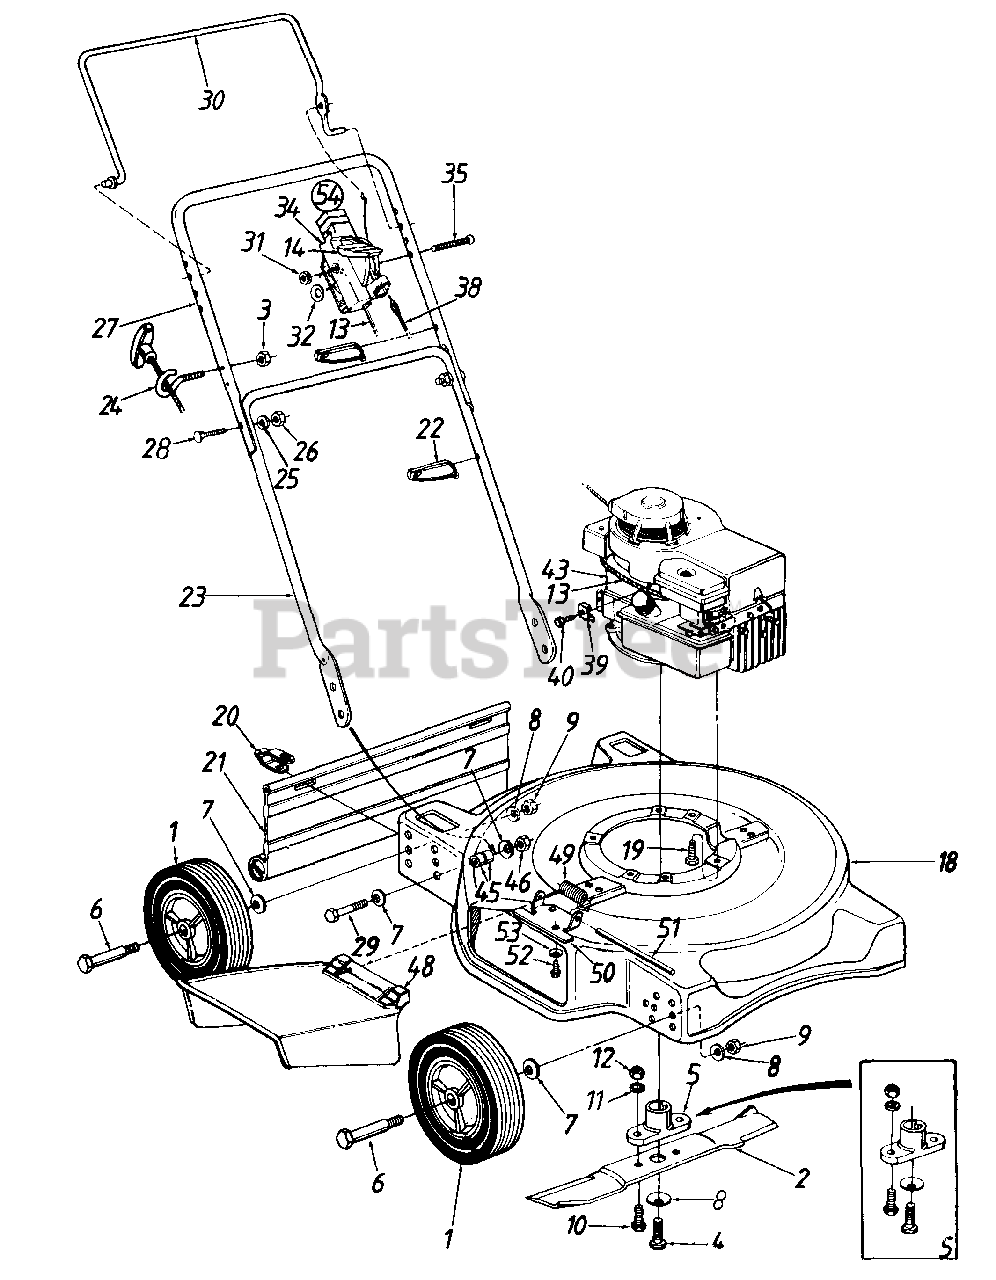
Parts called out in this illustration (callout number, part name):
1	Wheel Ass'y. Comp. Rib Tread Plastic Rim (7")
2	20" Blade
3	Hex L-Nut 1/4-20 Thd.
4	Hex Bolt 3/8-24 x 1.5" Lg.
5	Blade Adapter Kit
6	Axle Bolt
7	Bell-Wash..380" I.D. x .88"
8	Bell-Wash..39" I.D. x 1.13"
9	Hex Nut 3/8-16 Thd.
10	Hex Bolt 3/8-24 x 1" Lg.
11	L-Wash. 3/8" I.D.
12	Hex Nut 3/8-24 Thd.
13	Throttle Wire 51" Lg.
14	Throttle Lever
18	20" Deck Ass'y.
19	Hex Wash. Hd. Scr. 3/8-16 x 1" Lg.
20	Hinge Clip
21	Rear Flap 16.75" Lg.
22	Cable Tie
23	Lower Handle
24	Rope Guide Bolt
25	L-Wash. 5/16" I.D.
26	Hex Nut 5/16-18 Thd.
29	Hex Bolt 3/8-24 x 1.5" Lg.
31	Hex L-Nut 1/4-20 Thd.
32	Spr. Wash..66" I.D.
34	Throttle Body
35	Oval C-Sunk Scr.
38	Control Cable - 39"
39	Casing Clamp (B&S)
40	Hex Wash. Hd. Scr. #10-32 x .62" Lg.
43	Engine
45	Spacer .391" I.D. x .375" Lg.
46	Hex L-Nut 3/8-24 Thd.
48	Chute Deflector Ass'y.
49	Torsion Spring
50	Adapter Plate
51	Hinge Pin
52	Hex Self-Tap Scr. 1/4-20 x .5"
53	Bell-Wash. 1/4" I.D.
54	Throttle Box Comp.
